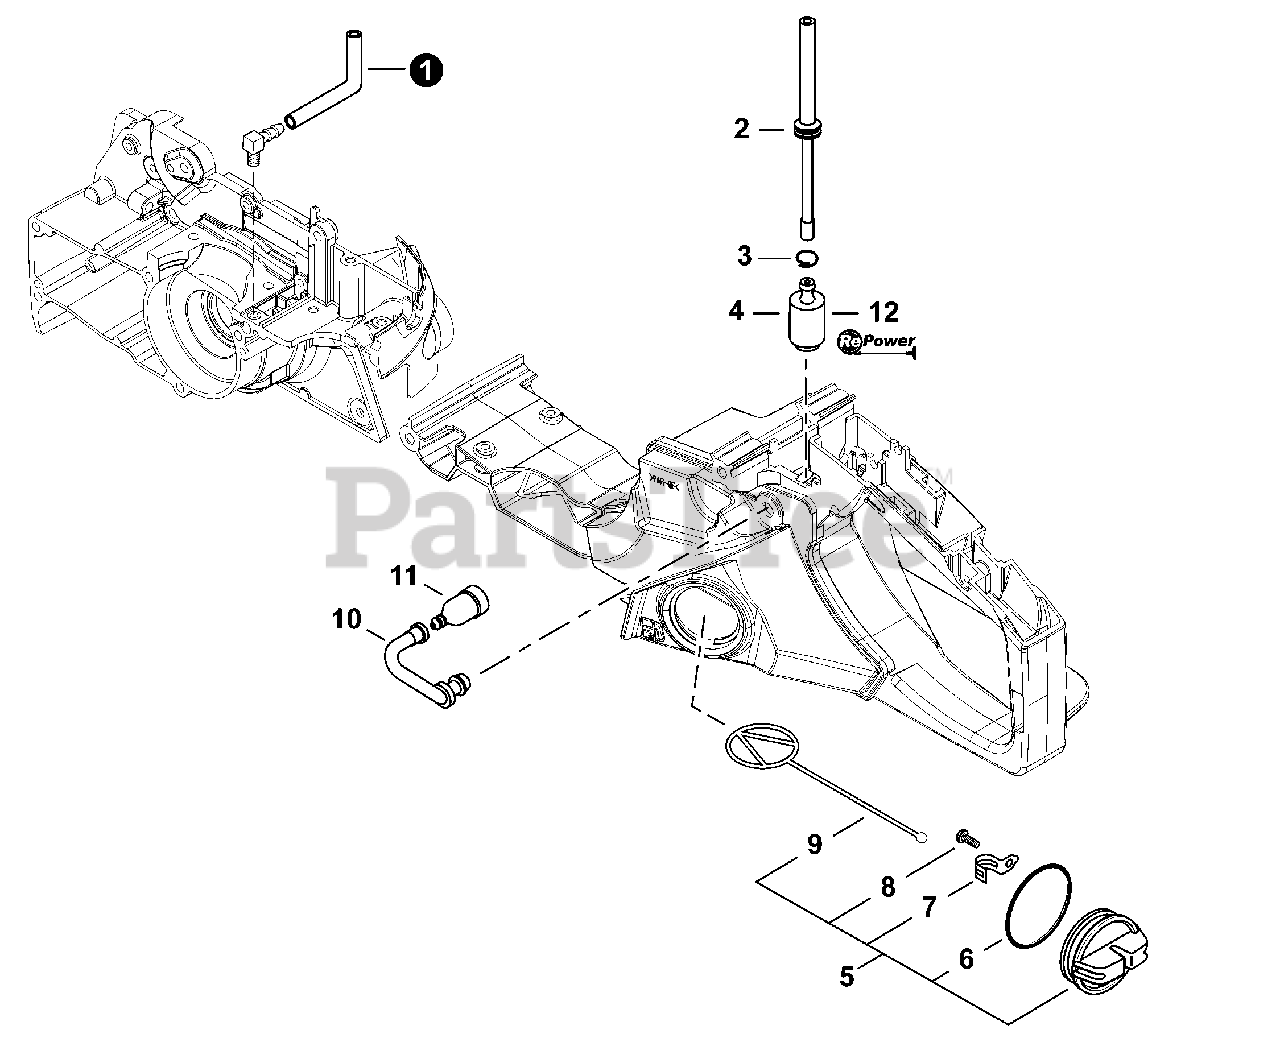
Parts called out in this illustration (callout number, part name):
1	PIPE, PULSE
2	FUEL SYSTEM KIT - REPOWER
3	PIPE, FUEL 3×6×75
4	CONNECTOR, PIPE
5	PIPE, FUEL
6	CLIP Ø6
7	FILTER, FUEL
8	O-RING 29
9	CAP ASSY, FUEL
10	O-RING 29
11	RETAINER, CONNECTOR
12	SCREW, TAPPING 3×8
13	CONNECTOR, CAP L= 60mm
14	PIPE, FUEL VENT
15	VENT ASSY
16	TUNE-UP KIT - REPOWER
